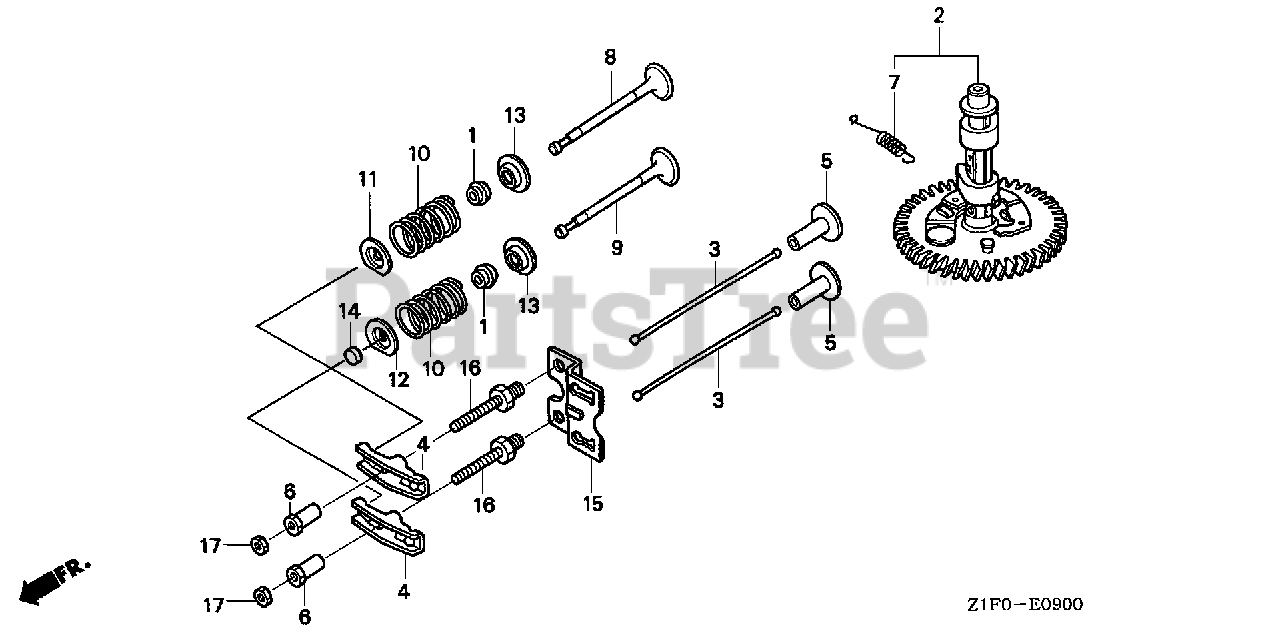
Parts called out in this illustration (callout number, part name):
1	SEAL, VALVE STEM
2	CAMSHAFT ASSY.
4	ARM, VALVE ROCKER
5	LIFTER, VALVE
6	PIVOT, ROCKER ARM
7	SPRING, WEIGHT RETURN
8	VALVE, IN.
9	VALVE, EX. (STELITE)
10	SPRING, VALVE
11	RETAINER, IN. VALVE SPRING (EXHAUST SIDE)
12	RETAINER, IN. VALVE SPRING (EXHAUST SIDE)
13	SEAT, VALVE SPRING
15	GUIDE, PUSH ROD
16	BOLT, PIVOT (8MM)
17	NUT, PIVOT ADJ.
